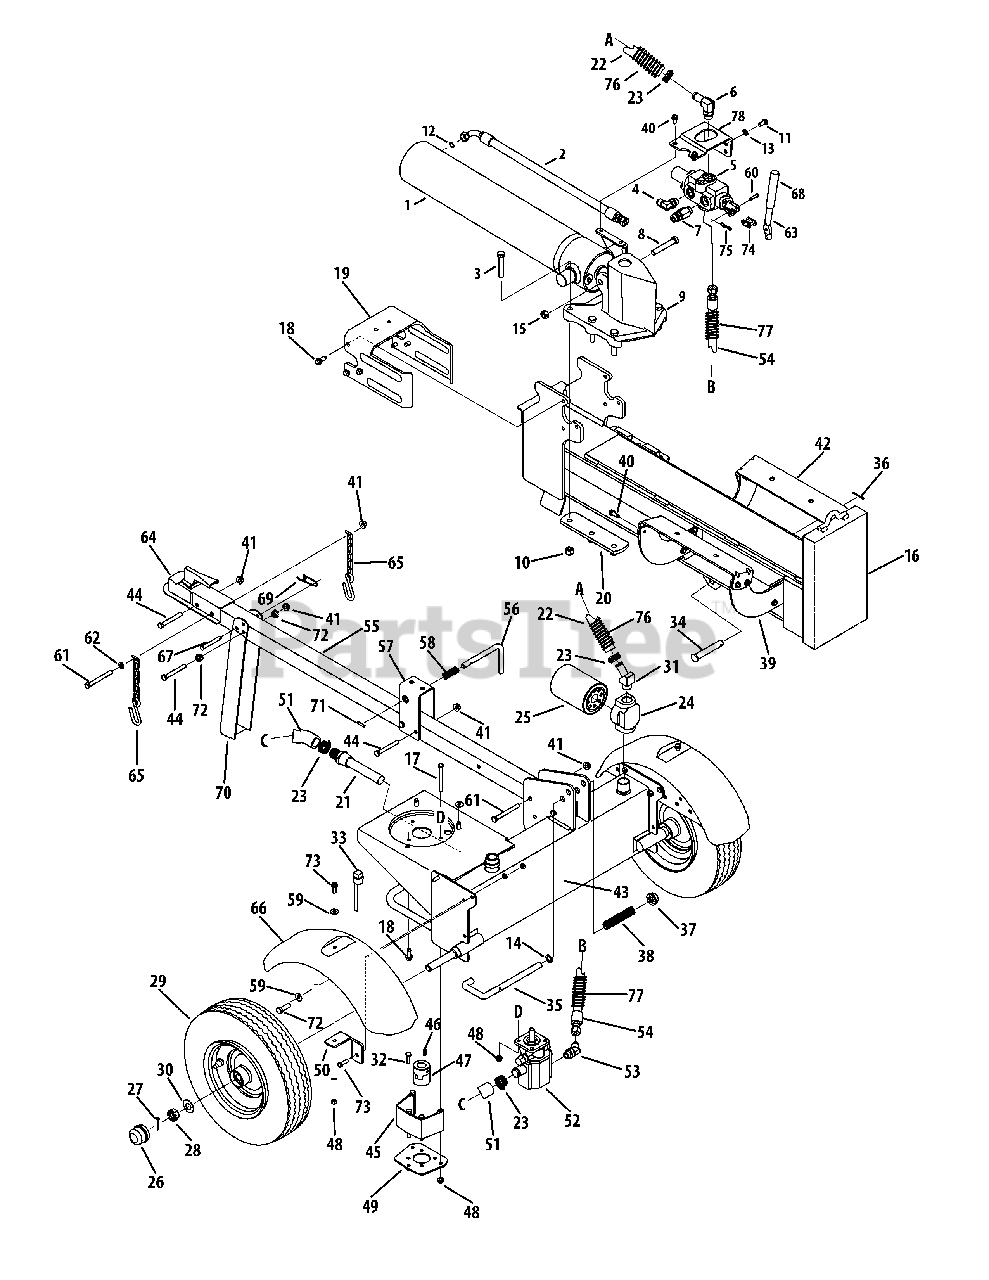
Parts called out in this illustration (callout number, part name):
1	Hydraulic Cylinder
2	Hydraulic Tube
3	Hex Cap Screw, 1/2-20 x 2.75
4	90 Degree Solid Adapter
5	Control Valve
6	Return Elbow
7	Nipple Pipe, 1/2-14
8	Hex Cap Screw, 1/2-13 x 3.25
9	Wedge Assembly
10	Hex Lock Nut, 1/2-20
11	Hex Cap Screw, 3/8-16 x .75
12	O-Ring, .419 ID x .070 Dia.
13	Lock Washer, 3/8
14	Flat Washer, .635 x.93 x.06
15	Hex Lock Nut, 1/2-13
16	Beam Assembly
17	Hex Screw, 5/16-18 x 3.25
18	Self Tapping Screw, 3/8-16 x 1.0
19	Dislodger Bracket
20	Back Plate
21	Inlet Filter
22	Return Hose, 3/4 x 44
23	Hose Clamp, 5/8
24	Filter Housing
25	Oil Filter
26	Hub Cap
27	Cotter Pin
28	Slotted Nut, 3/4-16
29	Complete Wheel Assembly
29	Dust Seal
29	Roller Bearing
30	Flat Washer, .760 x.500
31	Hydraulic Fitting, 1 1/16 Orb x .75
32	Hex Screw, 5/16-18 x 1.00
33	Vented Dipstick
34	Clevis Pin
35	Lock Rod
36	Cotter Pin
37	Push Cap
38	Compression Spring
39	Log Tray Bracket
40	Hex Washer Screw, 5/16-18 x .750
41	Flange Lock Nut, 3/8-16
43	Frame Assembly
44	Hex Bolt, 3/8-16 x 3
45	Coupling Shield
46	Square Key, 3/16" x .75
47	Log Splitter Coupling
47	Coupling, .500
47	Coupling, .875
47	Spider Bushing
47	Set Screws
48	Flange Lock Nut, 5/16-18
49	Rear Coupling Support Bracket
50	Fender Mounting Bracket
51	Hose
52	Gear Pump
53	45 Degree Elbow Fitting
54	High Pressure Hydraulic Hose
55	Tongue Assembly
56	Latch Rod
58	Compression Spring
59	Flat Washer
60	Clevis Pin
61	Hex Cap Screw, 3/8-16 x 3.50
62	Flat Washer, .375 x.738 x.063
63	Hydraulic Valve Control
64	Hitch Coupling Assembly
66	Fender
67	Clevis Pin
69	Spring Pin
70	Jack Stand
71	Spiral Pin
72	Plastic Bushing, .380 ID
73	Self-Tapping Screw, 5/16-18 x 1.00
74	Valve Handle Link
75	Cotter Pin, Bow Tie
76	Hose Guard, 48"
77	Hose Guard, 44"
78	Outer Valve Bracket
